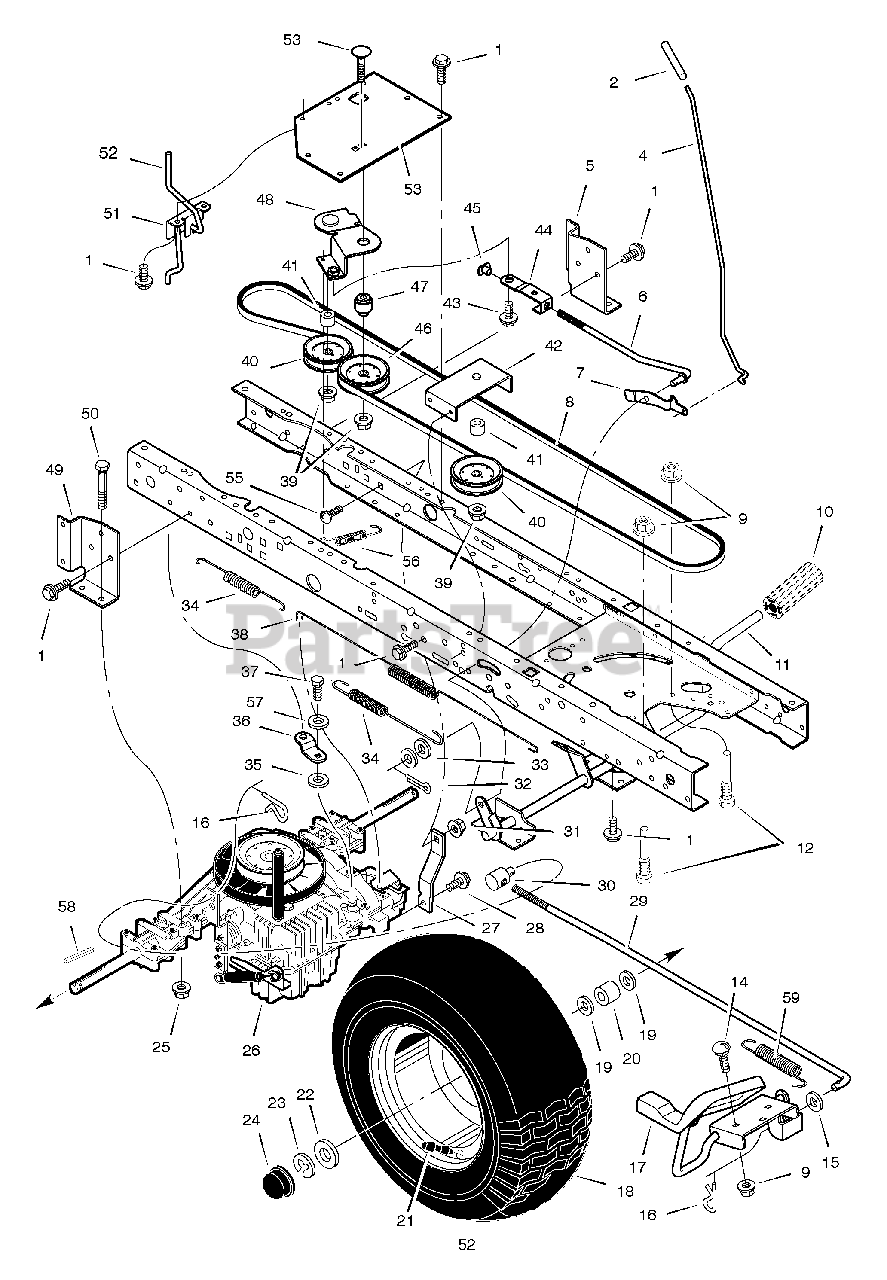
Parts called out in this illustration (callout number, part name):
1	Screw
2	Grip, Parking Brake
4	Rod, Parking Brake
5	Bracket, Transaxle - Left
6	Rod, Clutch
7	Latch, Parking Brake
8	V-Belt, Drive
9	Nut, Flange
10	Pedal, Brake/Clutch
11	Assembly, Brake Pedal
12	Screw, Guide
14	Bolt, Carriage
16	Pin, Hair
17	Pedal Assembly, Hydro
18	Wheel & Tire Ass'y - Rear 20"
20	Spacer
21	Stem, Valve
24	Cap, Hub
25	Nut, Centerlock
26	Transaxle **
27	Strap, Torque
29	Rod, Control
30	NUT, Adjusting
31	Nut, Centerlock
32	Pin, Cotter
34	Spring, Extension
36	ARM, Disconnect
37	Capscrew
38	Spring, Brake
39	Locknut, Flange
40	Pulley, Idler
42	Bracket, Idler Assembly
43	Bolt, Shoulder
44	Link, Clutch
45	Nut, Tee
46	Pulley, Idler
47	Bushing, Pivot
48	Arm Assembly, Idler
49	Bracket, Transaxle -Right
50	Bolt, Hex
51	Bracket, Disconnect
52	Rod, Disconnect
53	Bracket, Idler Pivot
54	Bolt, Carriage
55	Bolt, Carriage
56	Spring, Clutch
58	Key, Square
59	Spring
